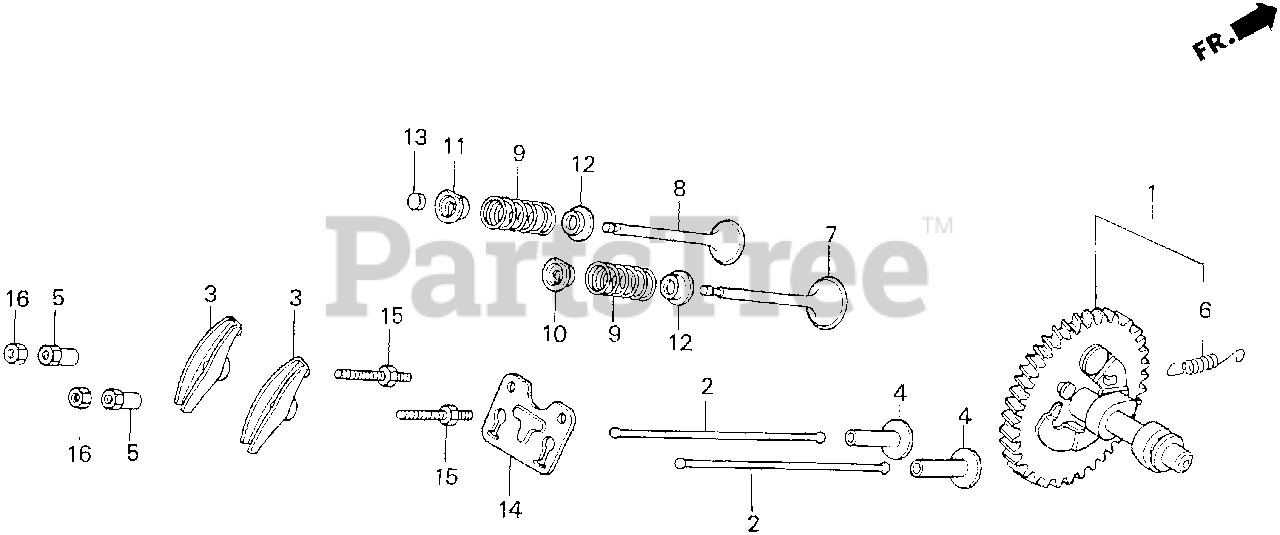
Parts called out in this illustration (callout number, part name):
1	CAMSHAFT ASSY.
2	ROD, PUSH
3	ARM, VALVE ROCKER
4	LIFTER, VALVE
5	PIVOT, ROCKER ARM
6	SPRING, WEIGHT RETURN
7	VALVE, IN.
8	VALVE, EX. (STELITE)
9	SPRING, VALVE
10	RETAINER, IN. VALVE SPRING
11	RETAINER, EX. VALVE SPRING
12	SEAT, VALVE SPRING
13	ROTATOR, VALVE
14	PLATE, PUSH ROD GUIDE
15	BOLT, PIVOT (8MM)
16	NUT, PIVOT ADJ.
